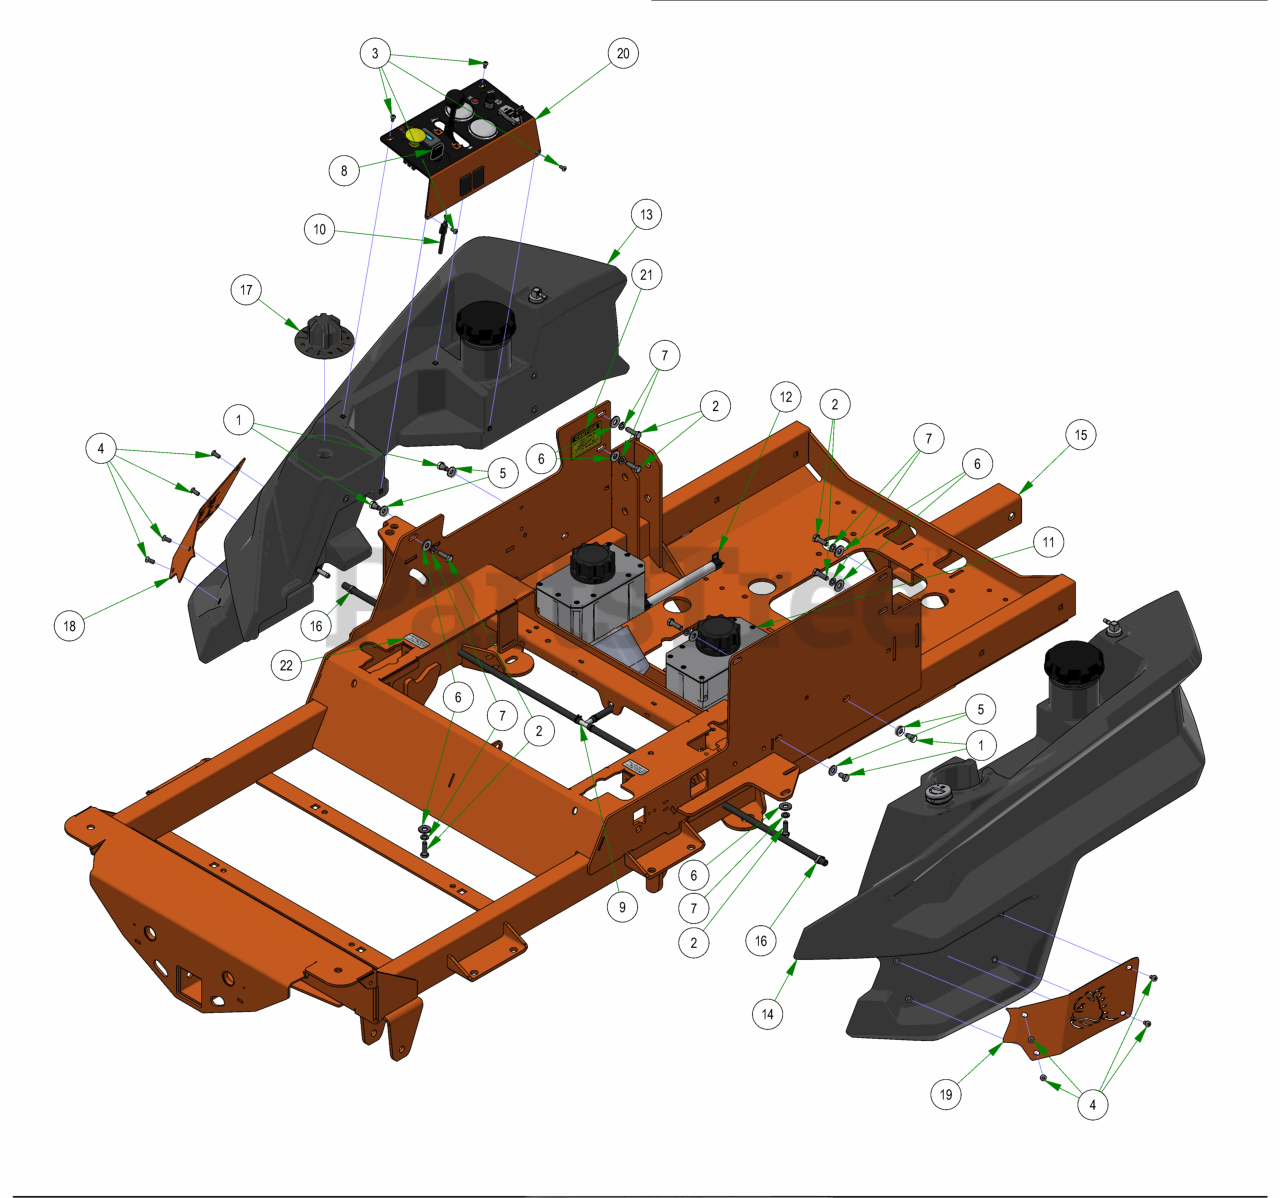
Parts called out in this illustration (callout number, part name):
1	5/16-18 X 1/2 HEX CAP SCREW (GR.5) ZINC
2	5/16-18 X 1 HEX CAP SCREW (GR.5) ZINC
3	10-32 X 3/8 BUTTON SOCKET CAP SCREW 18-8 STAINLESS STEEL
4	1/4-20 X 1/2 BUTTON SOCKET CAP SCREW 18-8 STAINLESS STEEL
5	1/4 USS FLAT WASHER (3/4 OD) ZINC
6	5/16 USS FLAT WASHER (7/8 OD) ZINC
7	5/16 SPLIT LOCKWASHER ZINC
8	Ignition Key
9	2022 Renegade Diesel Fuel Line Assembly
10	Diesel Throttle Cable
11	LH Rogue Hydro Tank Assy
12	RH Rogue Hydro Tank Assy
13	2019 Right Renagade Fuel Tank (diesel)
14	2019 Left Renegade Fuel Tank (Diesel)
15	2022 Horizontal Diesel Frame
16	2 EAR CLAMP 12.5mm-15mm
17	2019 Deck Height Dial
18	2019 Outlaw Fuel Tank Insert - Right
19	2019 Outlaw Fuel Tank Insert - Left
20	Renegade Control Panel Assembly
21	Hydraulic Decal
22	Low Sulfer Decal Tier 4 Diesel
